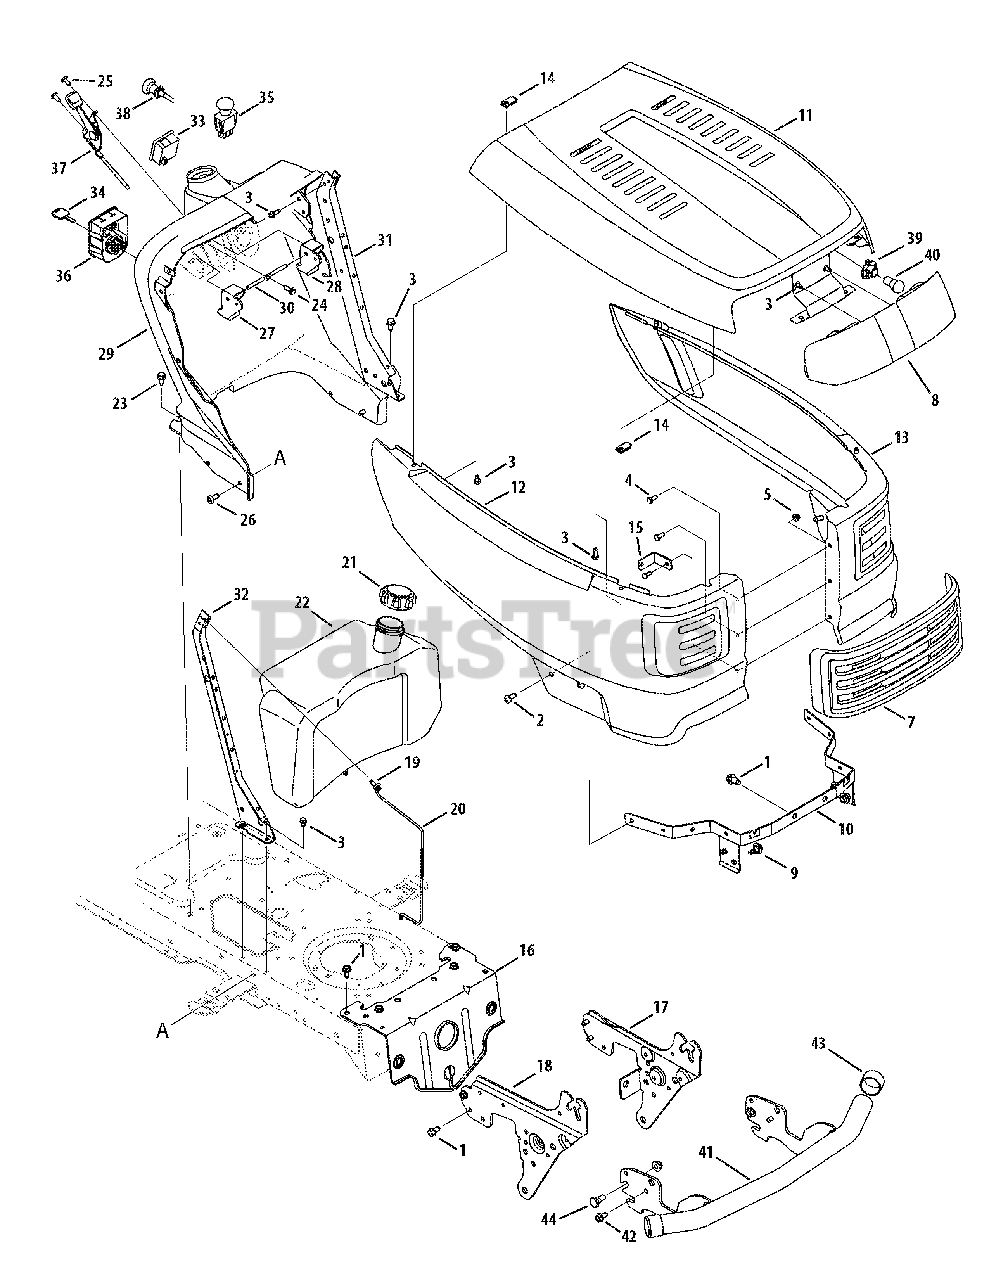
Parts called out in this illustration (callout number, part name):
1	Screw, 5/16-18 x .750
2	Screw, 5/16-18 x .375
3	Self-tapping Screw, 1/4-20 x.5
4	Hex Cap Screw, 1/4-20 x.62
5	Flange Lock Nut, 1/4-20
7	T-Style Grille Insert
9	Shoulder Screw,.43 x.29
14	T-Style Hood Fastener
20	Gas Tank Support Rod
21	Fuel Tank Cap
22	Fuel Tank, 2.5 gal.
23	Screw, 5/16-18 x 0.500
24	Screw, 1/4-15, .750
25	Screw, 1/4-14, 0.625
26	Screw, 5/16-18, 0.750
27	Dash Cruise Lever
28	Dash Brake Lever
29	Dash Panel, T-Style w/ Electric PTO
30	Bent Lever Rod
34	Ignition Key w/ plastic cover
34	Ignition Key w/o plastic cover
35	Electric PTO Switch
36	Ignition Switch
37	Throttle Control/Cable
38	Choke Control Cable
39	Headlight Socket
40	Lamp
42	Flange Lock Nut, 3/8-16
44	Shoulder Bolt, 3/8-16
